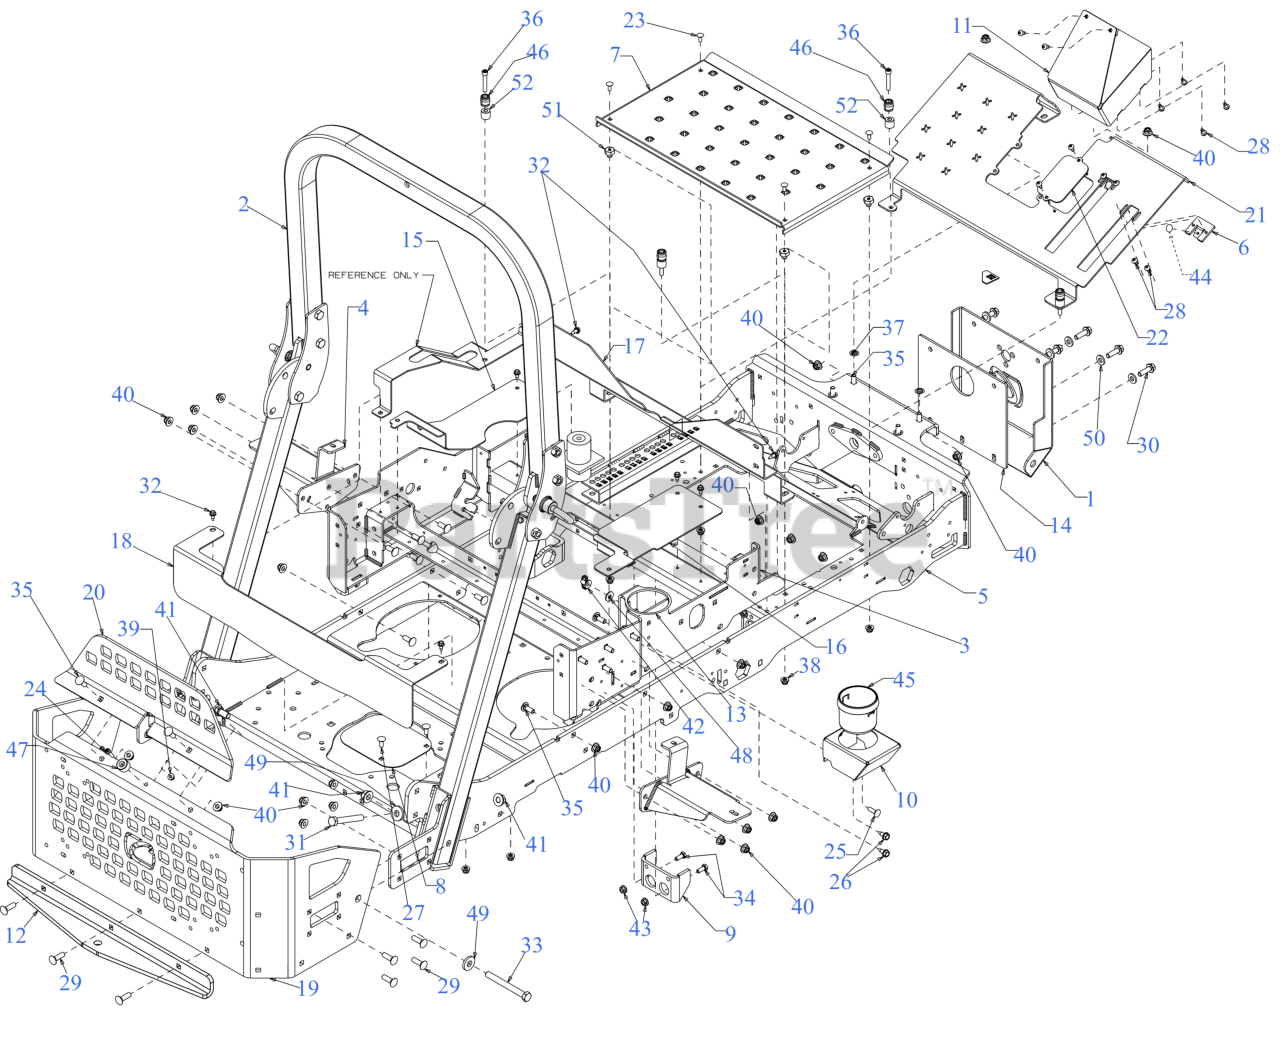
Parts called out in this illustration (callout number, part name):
2	PRO Z ROPS KIT
3	SEAT FRAME
4	FUEL TANK MOUNT
5	FRM ASM:RDR:CML:SDL:HG
6	REVERSE PEDAL STOP BRACKET
9	FRONT DECK LIFT MOUNTING BRACKET
10	LOWER CUP HOLDER
14	FRONT MOUNTING PLATE SPACER
15	SEAT COVER PANEL (LH)
16	SEAT COVER PANEL (RH)
17	SEAT BOX COVER (FRONT)
18	SEAT BOX COVER (REAR)
19	BUMPER (REAR)
20	BUMPER (UPPER RR)
21	FRONT PEDAL COVER
22	SERVICE DOOR
23	CARRIAGE BOLT 1/4-20 x .62
24	MACHINE SCREW 1/4-20:1
25	CARRIAGE BOLT 5/16-18 x 1.00
26	SCREW 5/16-18 x .750
27	CARRIAGE BOLT 5/16-18 x .75
28	SCREW 1/4-20 x .5
29	CARRIAGE BOLT 3/8-16 X1.25 GR5
30	SCREW 3/8-16 x 1.25 GR5
31	HEX SCREW 1/2-13 x 3.50
32	SCREW 1/4-20X.625
33	SCREW 1/2-13 x 4.5 GR 5
34	SCREW 5/16-18 x .75 GR5
35	CARRIAGE BOLT 3/8-16 x 1.00 GR5
36	SCREW 5/16-18X1.75 GR5
38	FLANGE LOCK NUT 5/16-18
39	FLANGE LOCK NUT
42	WING NUT 5/16-18
43	HEX FLANGE NUT
44	RATCHET CLIP
46	RADIAL BUMPER
48	FLAT WASHER
49	FLAT WASHER .531 x 1.25 x .181
50	FLAT WASHER
51	SHOULDER SPACER
